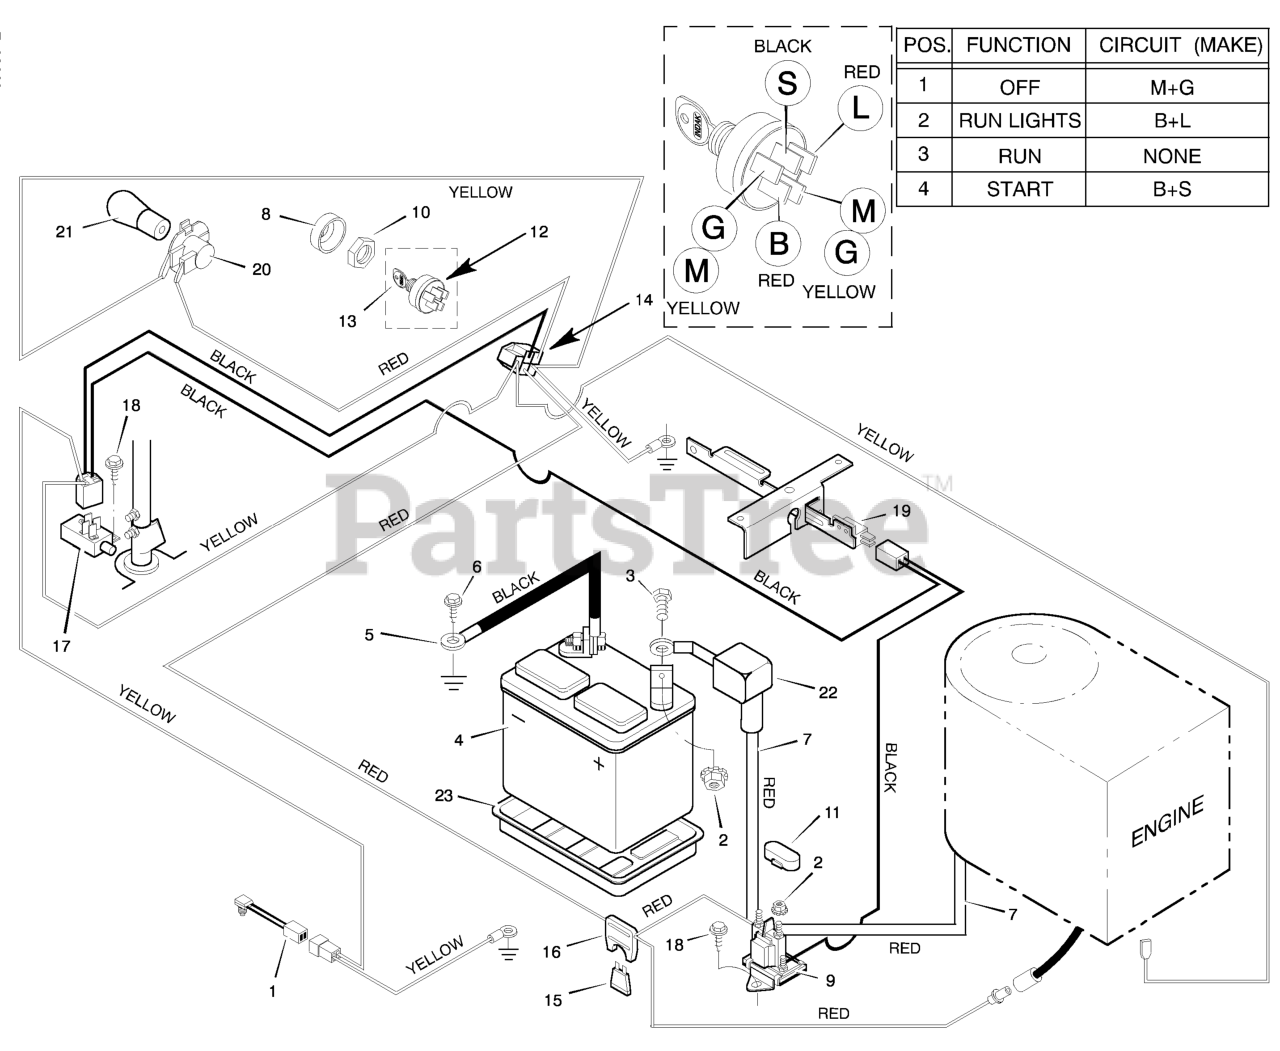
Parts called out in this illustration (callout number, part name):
1	Switch, Seat Sensor
2	Locknut
4	Battery
5	Cable, Battery Ground
7	Cable, Red Battery
8	Cap, Ignition
9	Solenoid
10	Nut, Hex
11	Cover, Solenoid
12	Switch, Ignition
13	Key, Ignition
14	Harness, Chassis Wire
16	Holder, Fuse
17	Switch, Limit
19	Switch, Limit
20	Socket, Light
21	Bulb, Light
22	Cover, Terminal
23	Tray, Battery
